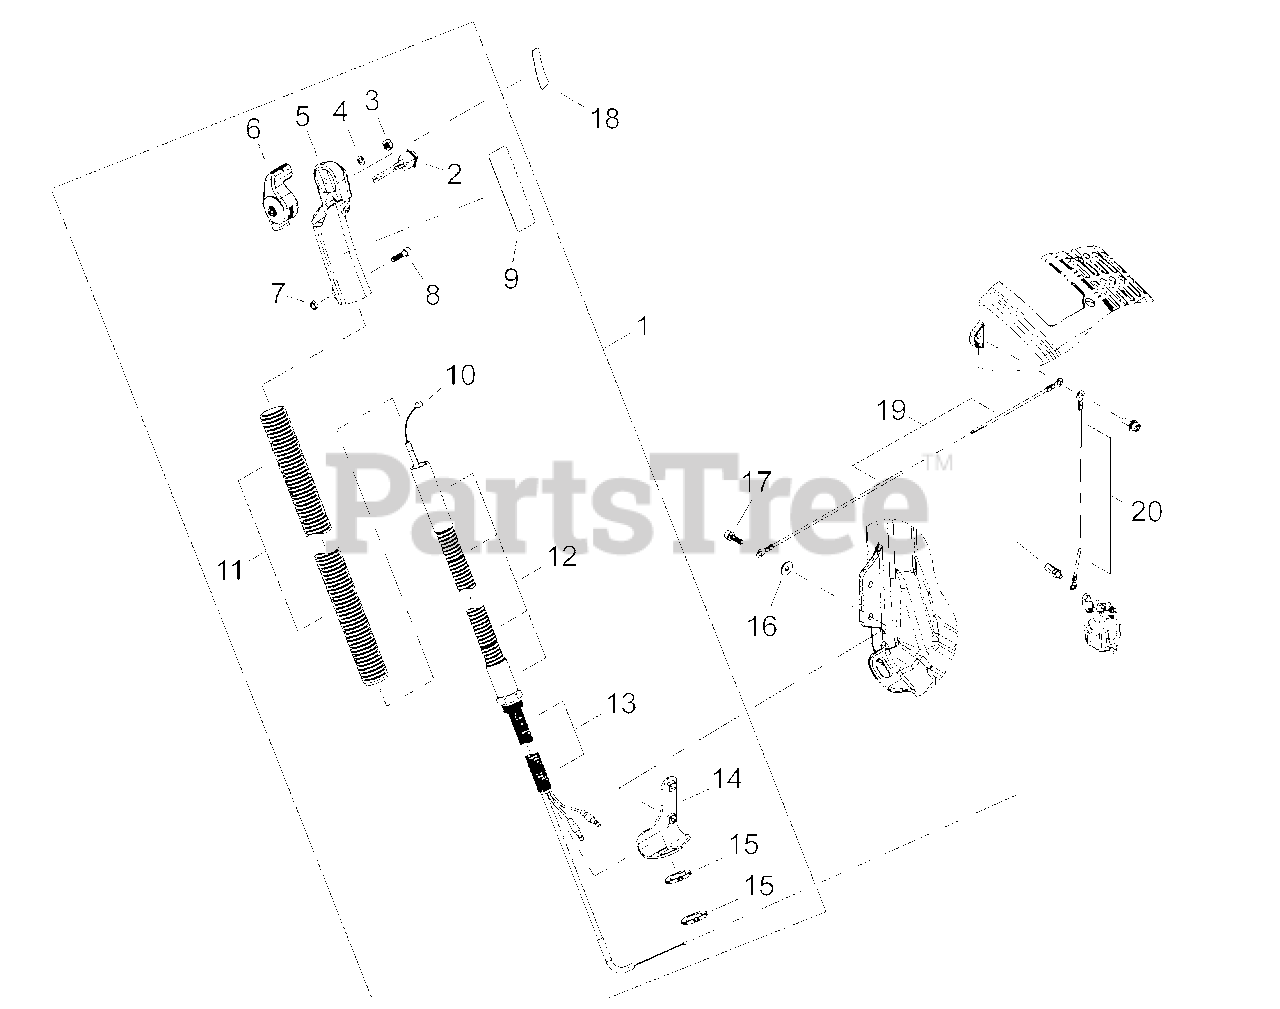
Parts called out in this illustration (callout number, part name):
1	THROTTLE CONTROL ASSY
2	SWITCH, ON-OFF
3	U-NUT M5
4	WASHER 5 MM
5	GRIP
6	CONTROL, THROTTLE
7	NUT M5
8	BOLT M5×16
9	PLATE, GROUND
10	CABLE, THROTTLE
11	TUBE, OUTER FLEX
12	ARM, FLEX
13	TUBE, FLEXIBLE
14	BRACKET, MOUNTING
15	NUT
16	WASHER Ø15ר5.2×1.6
17	BOLT, ADHESIVE M5×18
18	LABEL, THROTTLE
19	LEAD 0.75 MM2 L= 590
20	WIRE, STATIC DISCHARGE 110 MM
